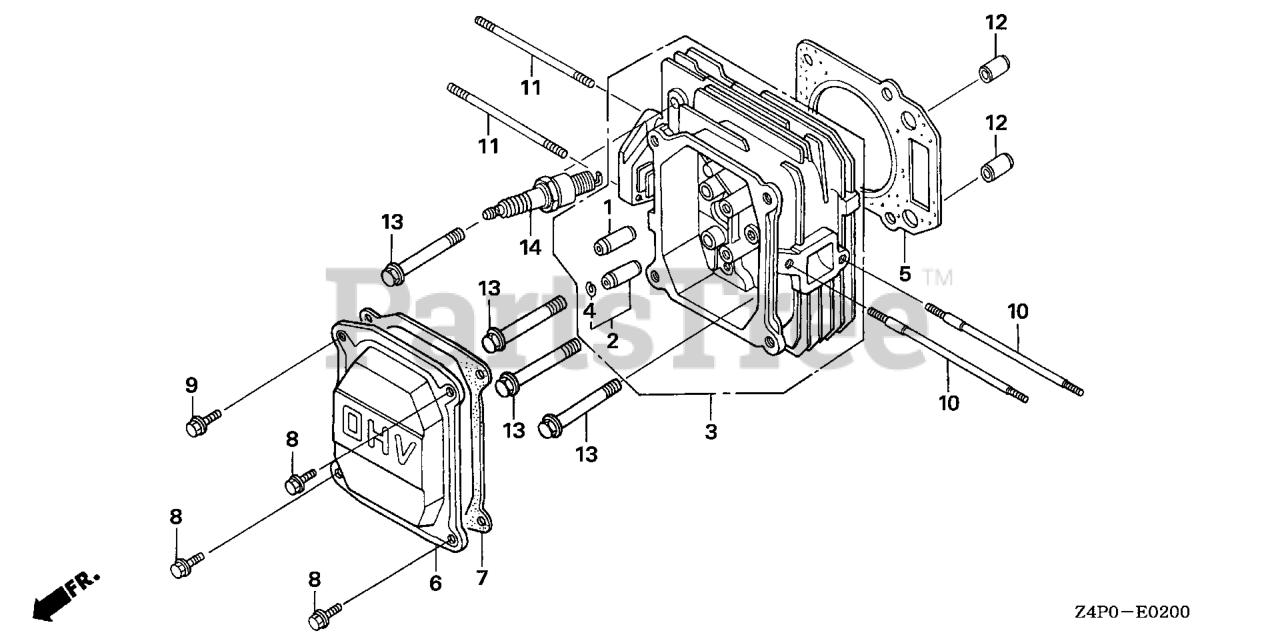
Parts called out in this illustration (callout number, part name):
3	CYLINDER HEAD
5	GASKET, CYLINDER HEAD (GUANGZHOU LEAKLESS)
5	GASKET, CYLINDER HEAD (NINGBO SIL GASKET)
6	COVER, HEAD
7	GASKET, HEAD COVER (NINGBO SIL GASKET)
7	GASKET, CYLINDER HEAD COVER
8	BOLT, FLANGE (6X14)
9	BOLT, FLANGE (6X14)
10	BOLT, STUD (6X97)
11	BOLT, STUD (6X85)
12	PIN A, DOWEL (10X16)
13	BOLT, FLANGE (8X50)
14	SPARK PLUG (BPR4ES) (NGK)
14	SPARK PLUG (W14EPR-U) (DENSO)
14	SPARK PLUG (BPR5ES) (NGK)
14	SPARK PLUG (W16EPR-U) (DENSO)
14	SPARK PLUG (BPR6ES) (NGK)
14	SPARK PLUG (W20EPR-U) (DENSO)
